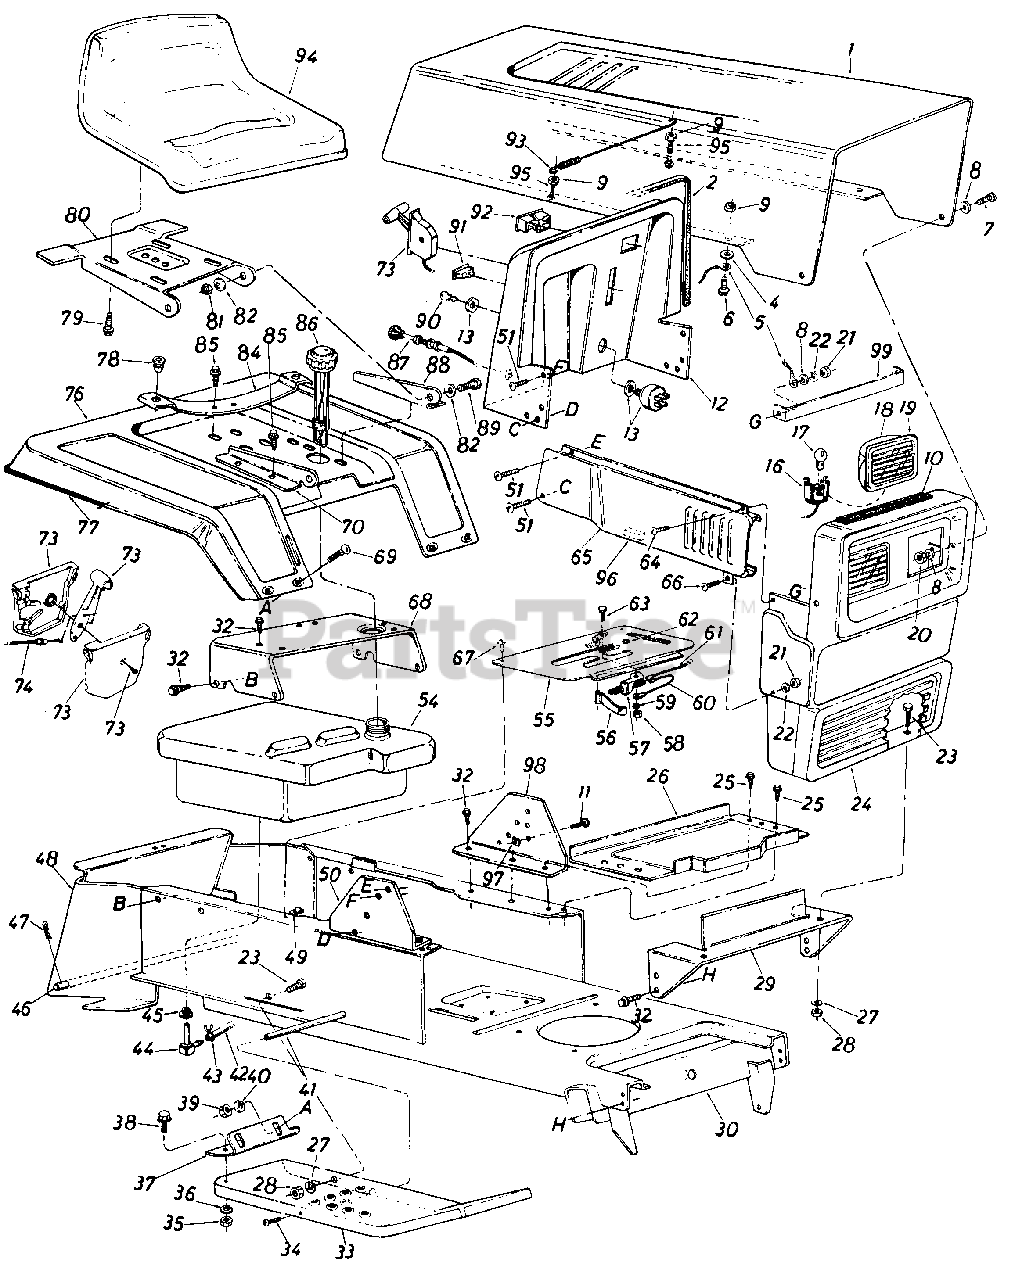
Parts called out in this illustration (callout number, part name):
1	Hood
2	Trim Strip 27" Lg.
4	Fl-Wash. .20" I.D. x .41" O.D.
5	Hood Stop
6	Truss Hd. Mach. Scr. #10-24 x .50" Lg.*
7	Hex Bolt 1/4-20 x .62" Lg.*
8	Fl-Wash. 1/4" I.D.*
9	Hex Sem Nut #10-24 Thd.*
10	Foam Strip 3/8 x 1" x 14"
11	Truss Mach. Scr. #10 x .50" Lg.
12	Dash Ass'y.
13	Ignition Switch
16	Socket
17	Lamp
18	Headlight Housing
19	Lens
20	Hex L-Nut 1/4-20 Thd.
21	Hex Nut 1/4-20 Thd.*
22	L-Wash. 1/4" I.D.*
23	Hex Bolt 5/16-18 x .75" Lg.*
24	Grille
25	Hex Wash. Hd. Scr. 1/4" x .50" Lg.
26	Battery Plate
27	L-Wash. 5/16" I.D.*
28	Hex Nut 5/16-18 Thd.*
29	Grille Mountir7g Bracket
30	Lower Frame Ass'y.
32	Hex Thd. Rolling Scr. 5/16-24 x .75" Lg.
33	Running Board R.H.
34	Truss Mach. Scr. 5/16-18 x .75" Lg.*
35	Hex Nut 5/16-18 Thd.*
36	Bell-Wash. .34" I.D. x .87" O.D.
39	Hex Nut 1/4-20 Thd.*
40	L-Wash. 1/4" I.D.*
41	Running Board Rod
42	Fuel Line 40" Lg.
43	Hose Clamp 3/8"
44	90ø Nipple
45	Bushing
46	Hitch Rod
47	Internal Cotterpin
48	Hitch Plate
49	Speed Nut
50	Dash Support Brk't. R.H.
51	Hex Wash. Hd. Tap Scr. 1/4 x .75" Lg.
54	Fuel Tank
55	Transmission Cover Ass'y.
56	Switch Actuator Spring Lever
57	Safety Switch
58	Hex Nut 1/4-20 Thd.*
59	L-Wash. 1/4" I.D.
60	Electric Wire
61	Reverse Lockout Wire Harness
62	Snap Bushing
63	Hex Bolt 1/4-20 x .50" Lg.
64	Truss Hd. Scr. 1/4-20 x .75" Lg.*
65	Side Panel R.H.
66	Truss Mach. Scr. 1/4-20 x .50" Lg.
67	Truss Mach. "B" Tap Scr. #10 x .50" Lg.
68	Seat Mounting Channel
69	Carriage Bolt 1/4-20 x .50" Lg.*
70	Seat Bracket R.H.
73	Throttle Control Box Ass'y.
74	Throttle Control Wire
78	Grommet
79	Hex Wash. Hd. AB-Tap Scr. 3/8 x .75" Lg.
80	Seat Pivot Bracket
81	Hex Cent. L-Nut 5/16-18 Thd.
82	Belleville Wash. .34" I.D. x .88" O.D.
84	Seat Spring
85	Hex Wash. Hd. Self-Tap Scr. 5/16-18 x .50" Lg.
86	Gas Cap w/Gauge
87	Choke Control Comp.
88	Seat Bracket L.H.
89	Hex Bolt 5/16-18 x .75" Lg.
90	Ignition Key
91	Light Switch
92	Ammeter
93	Hood Spring
94	Seat Ass'y.
95	Hex Screw #10-24 x 1.0" Lg.
96	Rubber Strip 1/2" Sq. x 21/2" Lg.
97	Speed Nut
98	Dash Support Brk't. L.H.
99	Tie Strap Grille/Side Panel
